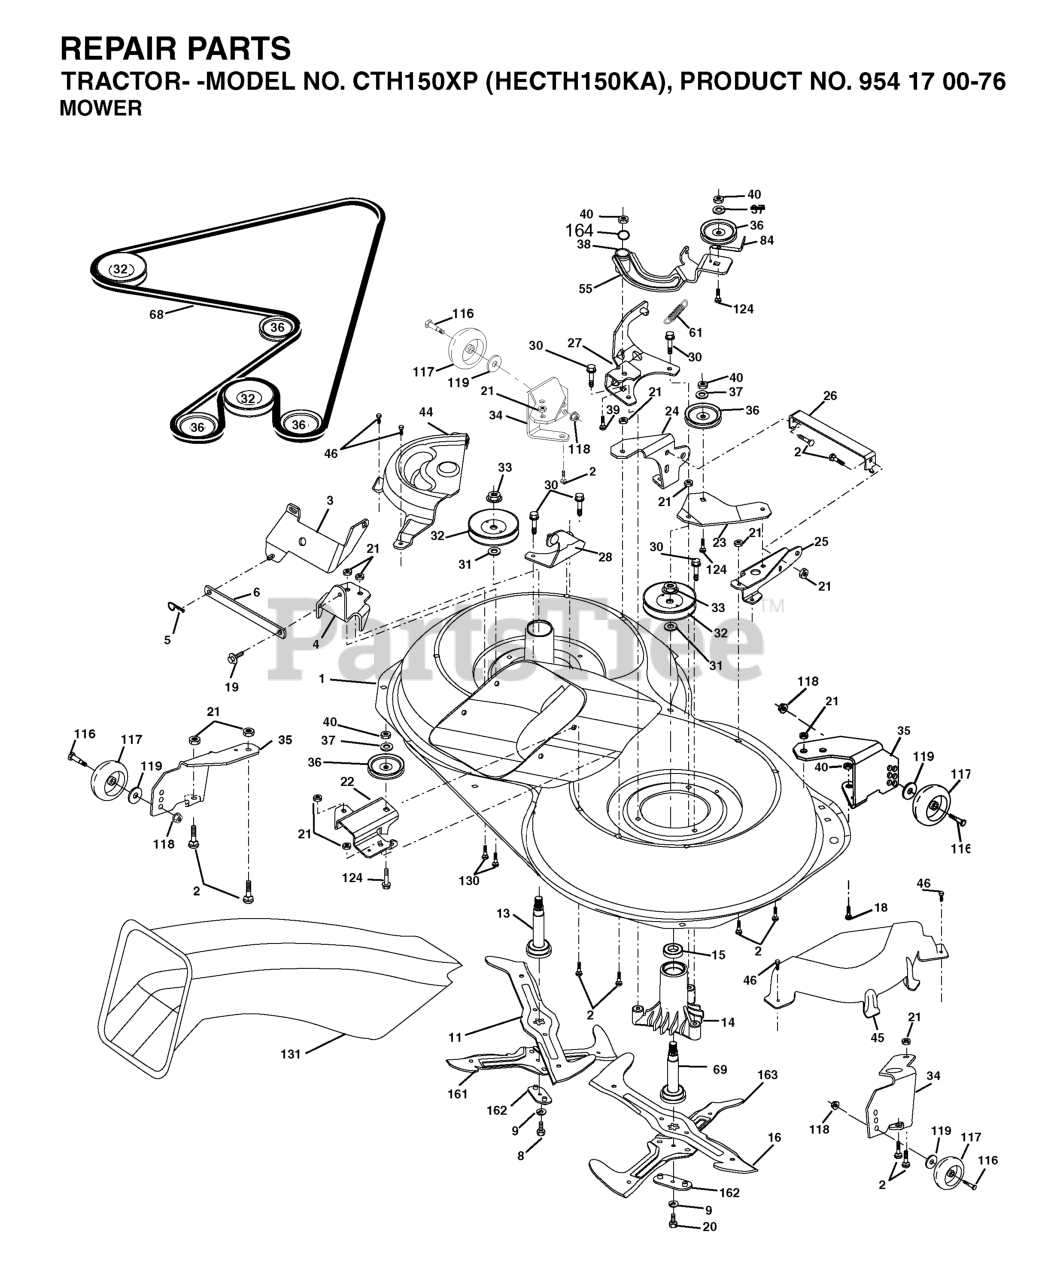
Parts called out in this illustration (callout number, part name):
1	Housing Asm. Mower 107 CRD
2	RP BOLT 5/16-18 X3/4 ZN/YEL GR
5	RETAINER-SPRNG RB
5	RETAINER SPRING
6	BAR.SWAY.92.CRD
8	BOLT.3/8-24X1.25 GR8
9	LOCKWASHER
11	BLADE.3N1.LH.CRD
13	SHAFT ASM VENT
14	HOUSING.MANDREL.VENTED (MACHD)
16	BLADE.3N1.RH.CRD
19	BOLT SHD 5/16-18
20	BOLT.3/8-24X1.25GR8. LHTHRD
21	LOCKNUT
22	BRACKET.IDLER.RR.107.CRD
25	BRACKET.SUSPENSION.RF.107.CRD
26	BRACE.SUPT.SUSP.FRT.CRD
28	BRACKET
30	SCREW, WASHER HEAD
31	WASHER.SPACER.MANDREL
33	NUT, FLG TOPLOCK 9/16"
36	PULLEY.IDLER.4.25
40	NUT LOCK FLG 3/8-16 UNC
45	COVER.MANDREL.RH.CRD
46	SCREW.1/4-20X5/8
55	ARM.IDLER.107.CRD
68	HEX-BELT 107 MOWER
69	SHAFT.ASM.W/LWR.BRG.RH.THREAD
84	KEEPER, BELT IDLER
116	SHOULDER BOLT
117	WHEEL GAGE DONUT
118	LOCKNUT
119	WASHER.5/16.FLAT.STE.STD.
124	BOLT.3/8-16X1.50
130	BOLT.CARR.SQNK.5/16-18UNC.X3/4
131	CHUTE BAGGER
163	BLADE.CROSS.RH.CRD.107
164	BRNG T
